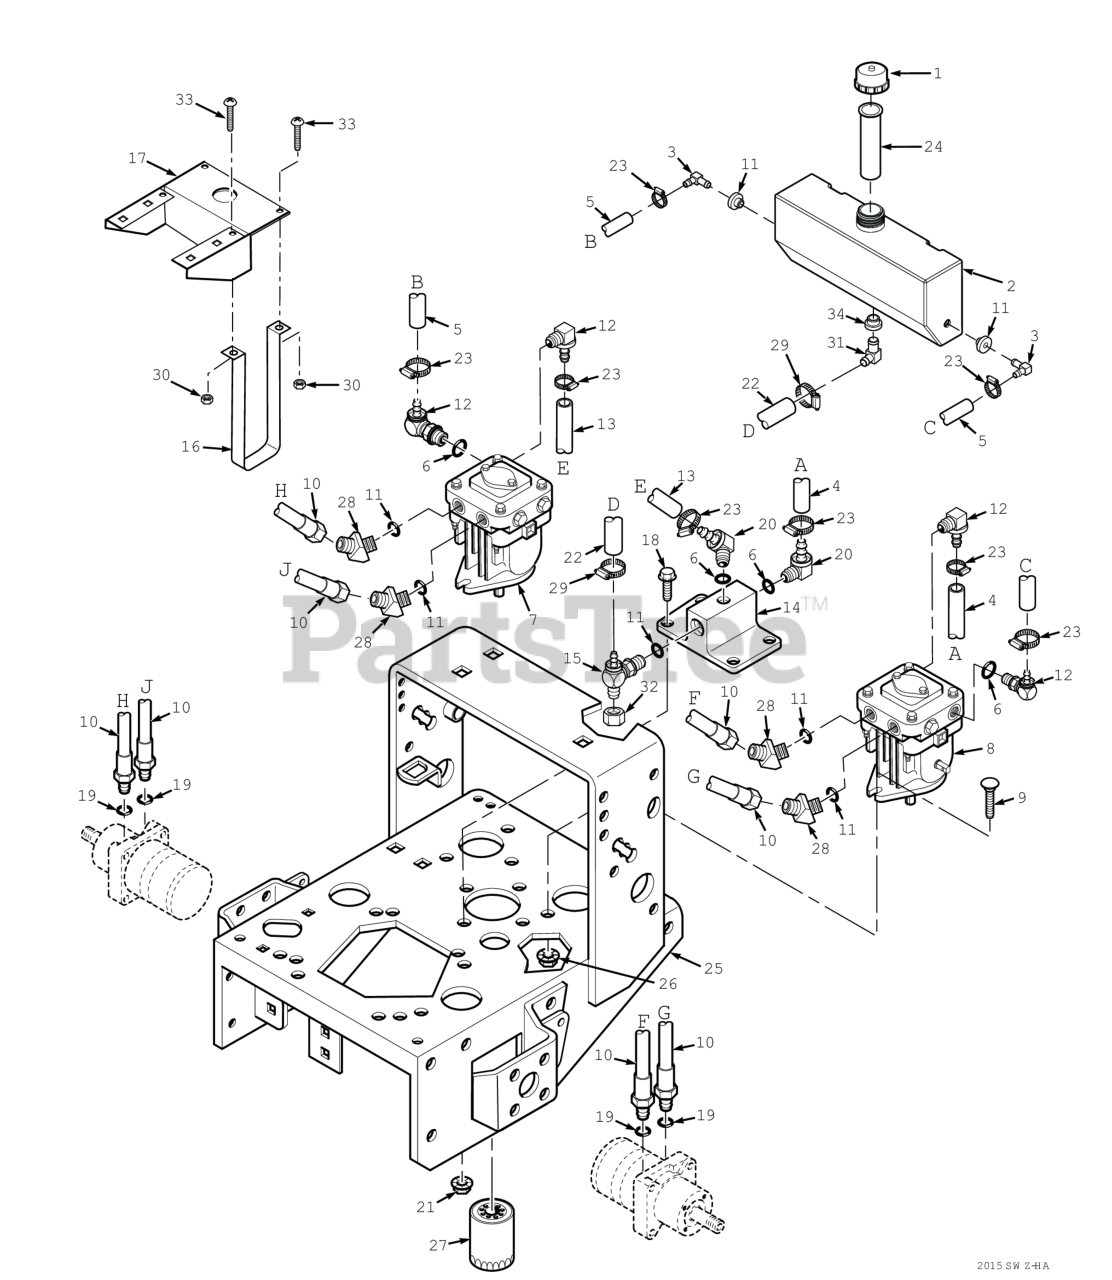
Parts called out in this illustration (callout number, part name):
1	CAP, HYDRAULIC TANK
2	Oil Reservoir (With Fittings)
3	Elbow, 90 Degree, 9/16-18 JIC x 9/16 O-Ring
4	Hose, 3/8" ID - 10-1/4" Long (Order By The Inch)
5	Hose, 3/8" ID - 10-1/4" Long (Order By The Inch)
6	"O" RING, 5/64 X 15/32 ID
7	Pump, PG-1JQQ-DY1X-XXXX (R.H.)
8	Pump, PG-1GQQ-DY1X-XXXX (L.H.)
9	SHORT SQ. NECK CARRIAGE BOLT, 3/8-16 X 1-1/4"
10	Hose, Pump to Wheel Motor
11	Bushing, 0.56" Dia. Viton
12	Elbow, 90 deg. 7/16-20 JIC to 9/16-18 "O" Ring
13	Hose, 3/8" ID - 10-1/4" Long (Order By The Inch)
14	Filter Head Assembly
15	Tee, 3/8" O-Ring x JIC x 1/2" Hose
16	Strap, Hydraulic Tank
17	Bracket, Hydraulic Tank
18	Capscrew, 5/16-18 x .75 Serrated Flange Hex Head
19	"O" RING, 3/32 X 3/4 ID
20	Elbow, 90 Degree - 9/16" O-Ring x 3/8" Hose
21	Nut, Serrated Flange 5/16-18 (Right Front Engine Mounting, Briggs and Kohler Only)
22	Hose, Formed 1/2" ID
23	Clamp, .69" Max. / .25" Min. Dia.
24	Insert, Filler Neck
25	Engine Deck (16" Wide) with Decals - Small Frame
26	NUT, 3/8-16 SERRATED FLANGE HEX HEAD
27	OIL FILTER, SPECIAL
28	Elbow, 45 Deg. - 3/4-16 JIC Male x Male 3/4-16 O-Ring
29	Clamp, Cable 3/4" I.D.
30	HEX, NUT, ELASTIC STOP LOCK, 1/4-20
31	Fitting, 90 Degree - 1/2" Hose
32	CAP, 3-4-16 JIC
33	Machine Screw, Round Head, 1/4-20 x 2.00"
34	Bushing, 0.78" Dia. Viton
